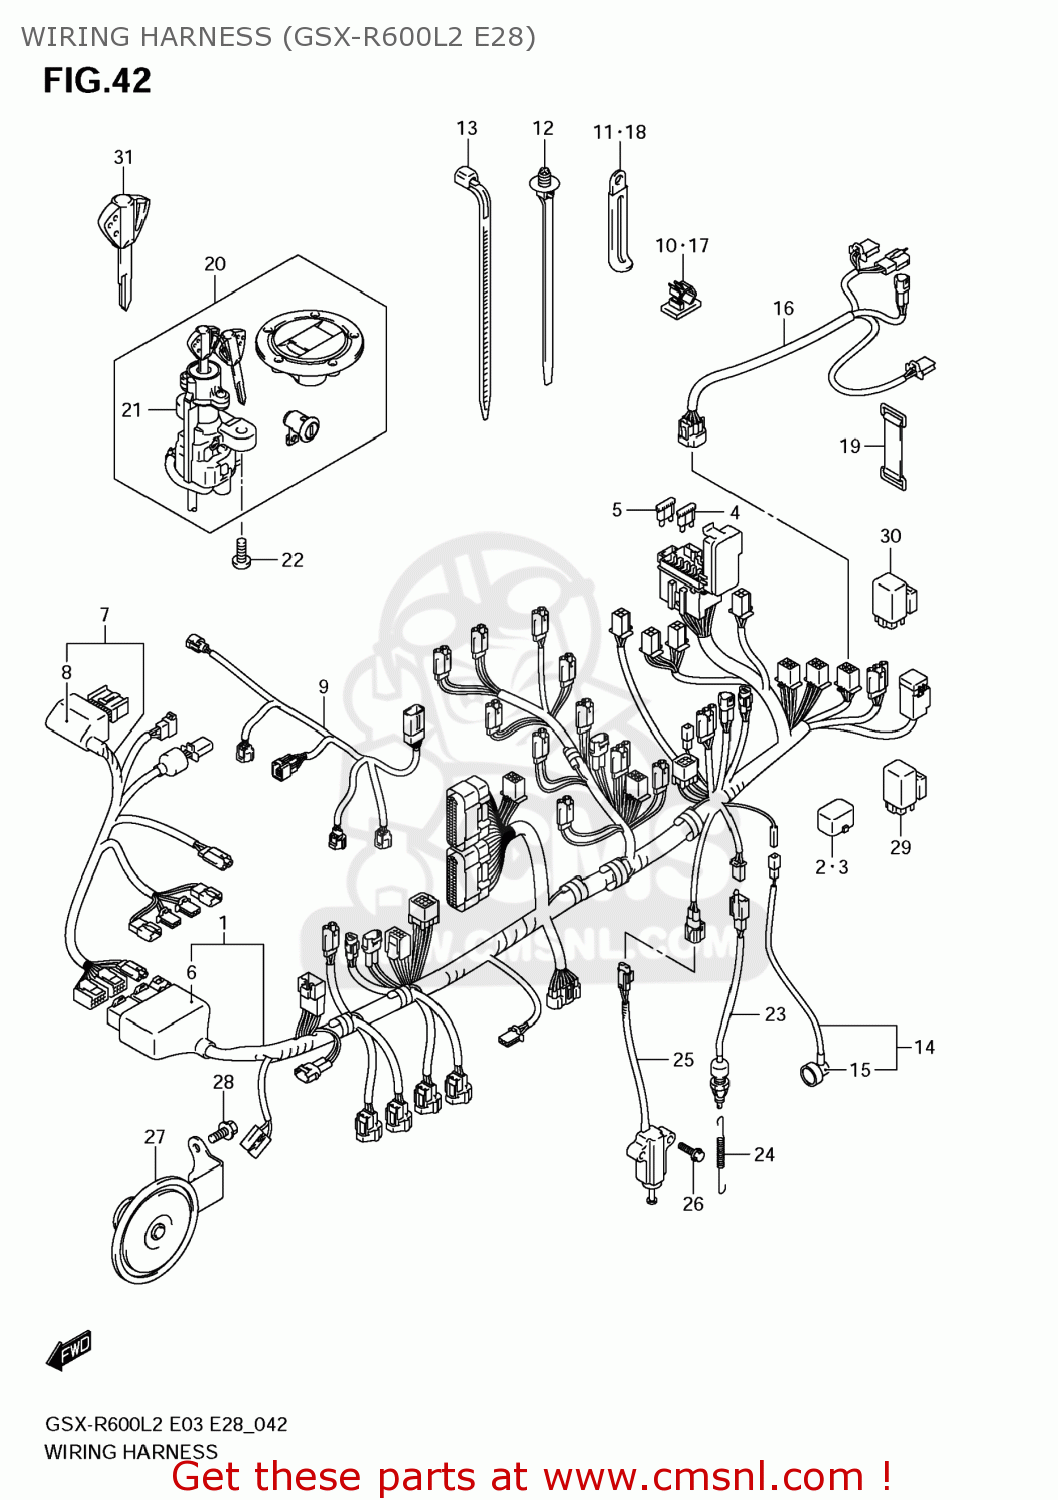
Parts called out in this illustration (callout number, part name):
1	HARNESS,WIRING NO.1
2	CAP,TS
3	CAP,CO ADJUST
4	FUSE(10A)
5	FUSE(15A)
6	COVER
7	HARNESS,WIRING NO.2
8	COVER,CONNECTOR
9	HARNESS,WIRING NO.3
10	CLAMP(L:95)
11	CLAMP(L:145)
12	CLAMP(L:154)
13	CLAMP(L:125)
14	WIRE,OIL PRESSURE SWITCH LEAD
15	CAP,OIL PRESSURE SWITCH
16	WIRE,RR COMB LEAD
17	CLAMP
18	CLAMP(L:45)
19	BAND
20	LOCK SET
21	LOCK ASSY,STEERING
22	BOLT(8X20)
23	SWITCH ASSY,STOP LAMP
24	SPRING
25	SWITCH ASSY,SIDE STAND
26	BOLT
27	HORN ASSY
28	BOLT
29	RELAY ASSY
30	RELAY ASSY
31	KEY,BLANK(IMMOBII)
